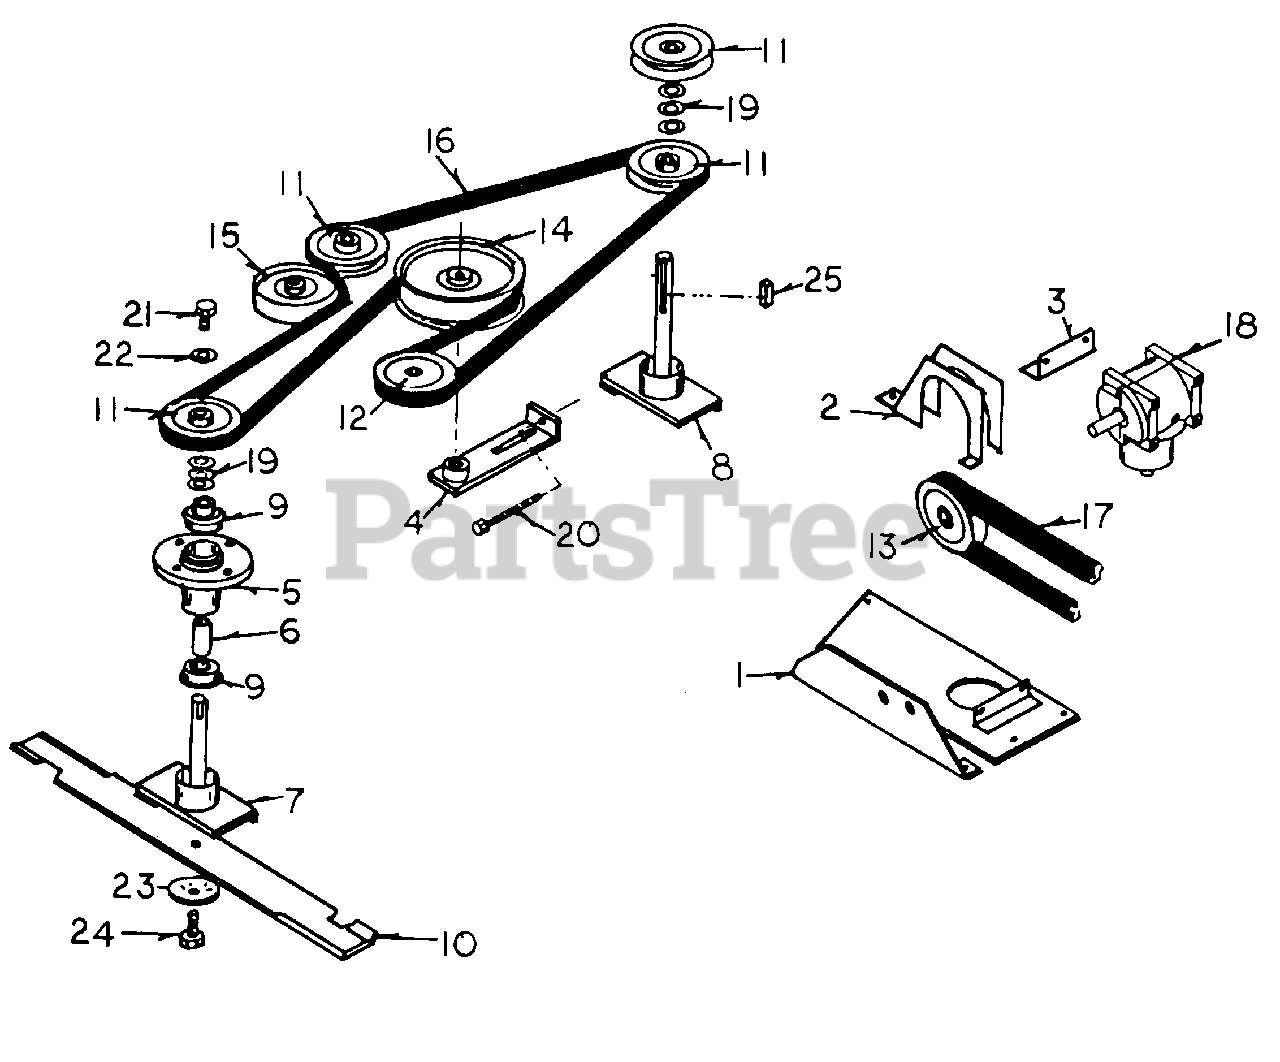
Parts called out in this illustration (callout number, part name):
2	Belt Guard
3	Gearbox Mount Angle
4	Belt Tightener
5	Spindle Housing
6	Spindle Spacer
7	Spindle Shaft
8	Spindle Shaft, Long
9	Spindle Bearing
11	Spindle Pulley
12	Gearbox Pulley, Out Put
13	Gearbox Pulley, In Put
14	Idler Pulley, Large
15	Idler Pulley, Small
17	Deck Drive Belt
20	Adjustment Bolt
21	Hex Bolt, 5/16-24 x 3/4"
22	Washer, 5/16", 10 Ga.
24	Hex Bolt, 3/8-24 x 1 1/14"
25	Key Stock, 3/16"
